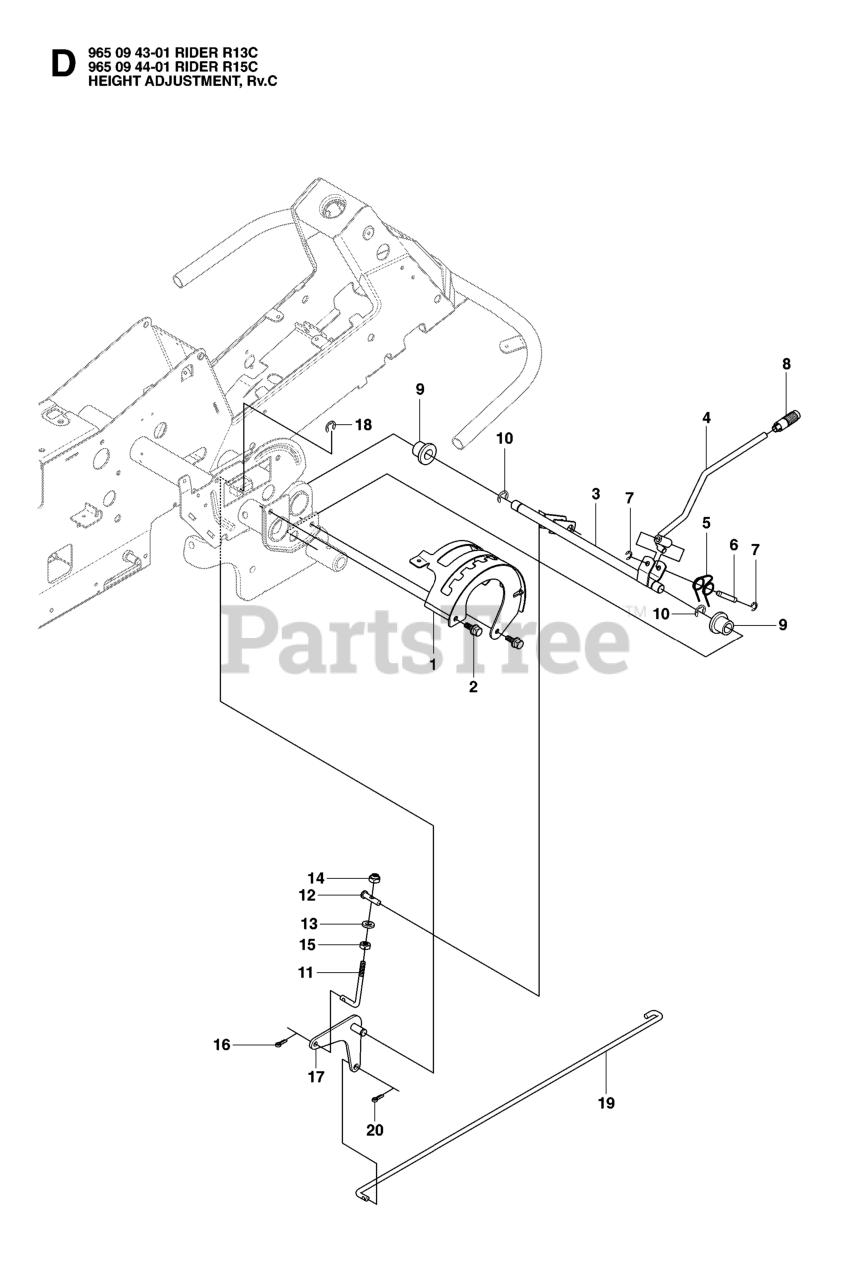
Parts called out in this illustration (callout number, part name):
1	CONTROL PLATE
3	HEIGHT ADJUSTER
4	HEIGHT ADJUSTER
5	HAIR PIN SPRING
8	GEAR STICK KNOB
9	BUSHING
13	WASHER
14	LOCKNUT M8
15	NUT
17	LINK HEIGHT ADJUSTMENT
18	RETAINING RING
19	CONNECTION ROD
